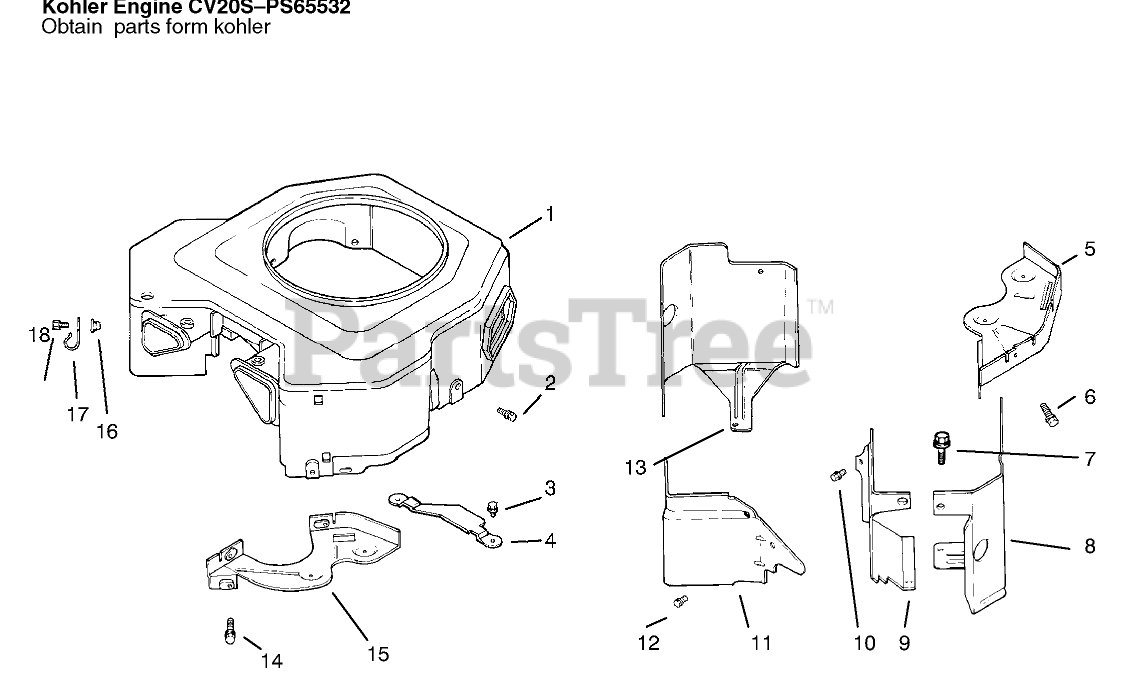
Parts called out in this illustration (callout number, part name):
1	Blower Housing ASM
3	Screw
4	Guard-Flywheel
5	Plate-Backing #2 Side
7	Screw
8	Baffle-Cylinder, #2
9	Baffle-Valley #1 Side
10	Screw
11	Baffle-Valley #2 Side
13	Baffle-Cylinder #1Side
14	Screw
15	Plate-Instruction
16	Nut
17	Clamp
18	Screw
